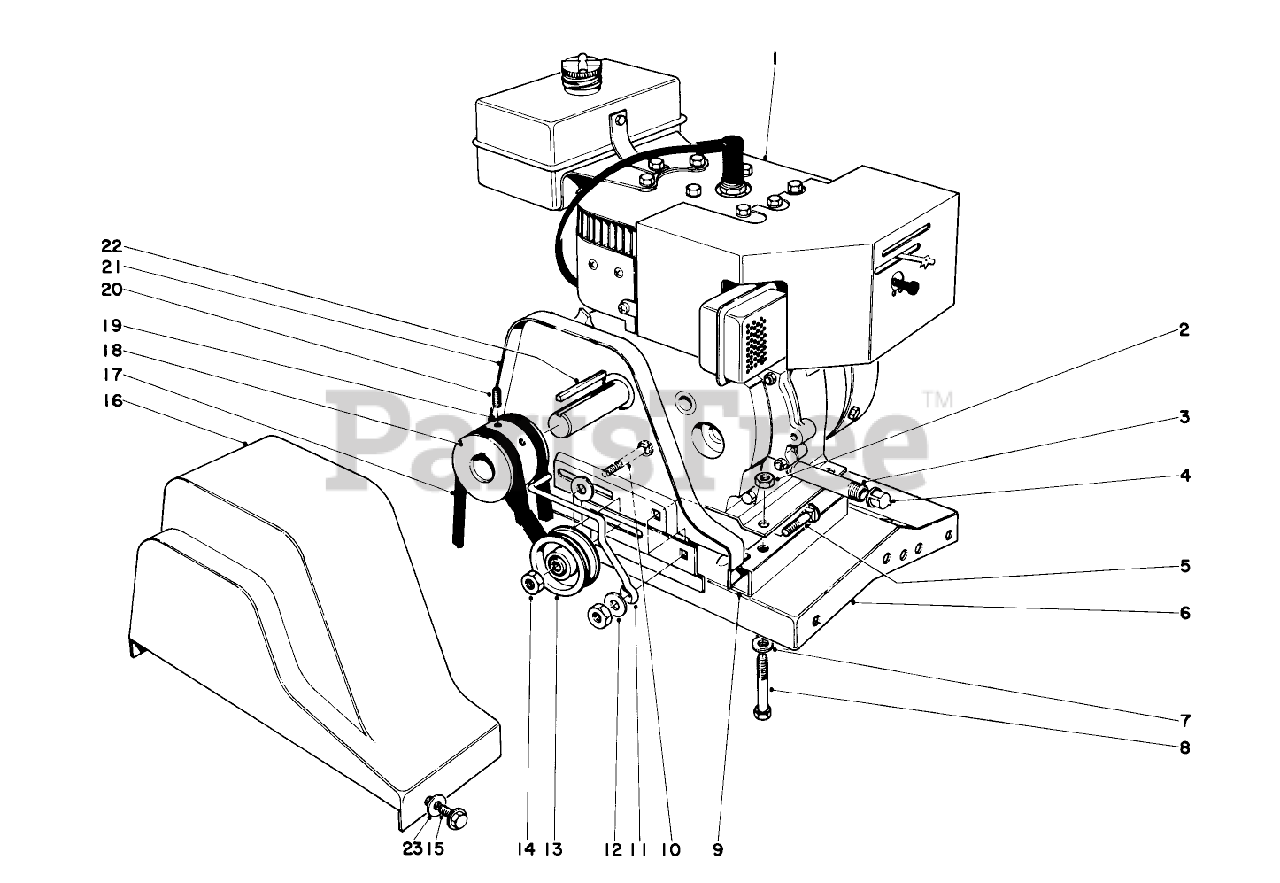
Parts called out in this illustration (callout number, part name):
1	Engine
2	Nut
3	NIPPLE-PIPE
4	CAP-PIPE
5	SCREW-CARR
6	Engine Base
7	WASHER-FLAT
8	SCREW-HH
9	Tube-Engine Mount
10	SCREW-CARR
11	BELT GUIDE
12	WASHER-FLAT
13	PULLEY-IDLER
14	NUT-HEX
15	1/4-20 X 1/2 SEMS MS
16	Belt Guard
17	V-Belt
18	Engine Pulley
19	V-Belt
20	1/4-20 X 5/8 SETSCREW
21	Belt Guard
23	WASHER-FLAT
